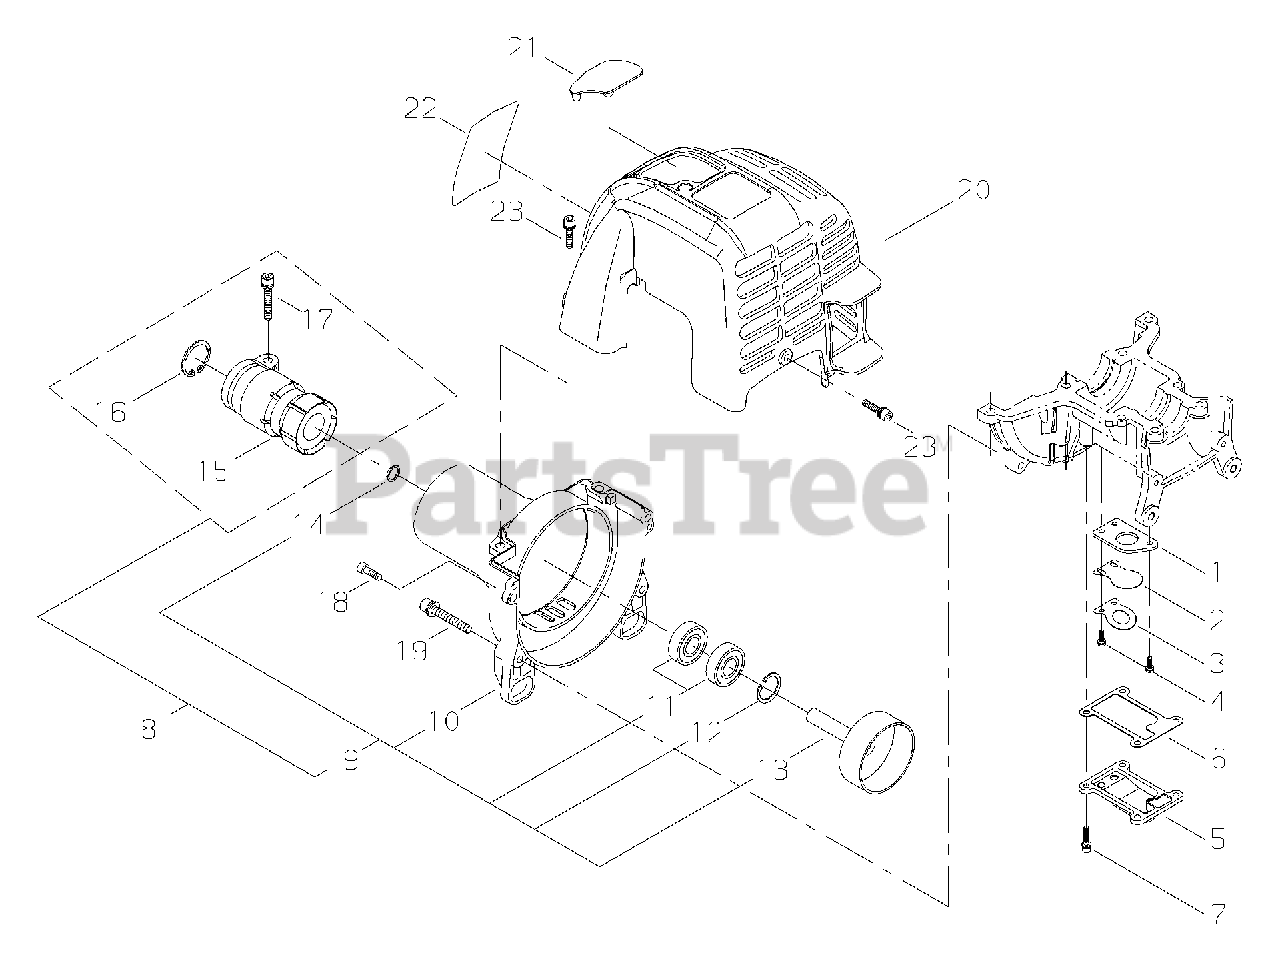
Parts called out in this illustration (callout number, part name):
1	PLATE, REED BACKING
2	VALVE, REED
3	STOP, REED VALVE
4	SCREW - 3X10
5	COVER, REED VALVE
6	GASKET, REED VALVE
7	SCREW - 4X14
8	FAN CASE ASSY
9	FAN CASE ASSY
10	CASE, FAN
11	BEARING, BALL - 6001DDUC3
12	RING, RETAINING - 28
13	DRUM, CLUTCH
14	RING, RETAINING
15	CLAMP, MAIN PIPE
16	RING, RETAINING - 42
17	SCREW - 5X22
18	SCREW - 5X16
19	SCREW - 5X40
20	COVER, ENGINE
21	COVER, SPARK PLUG
22	LABEL - MODEL DH2510
23	SCREW - 4X14
